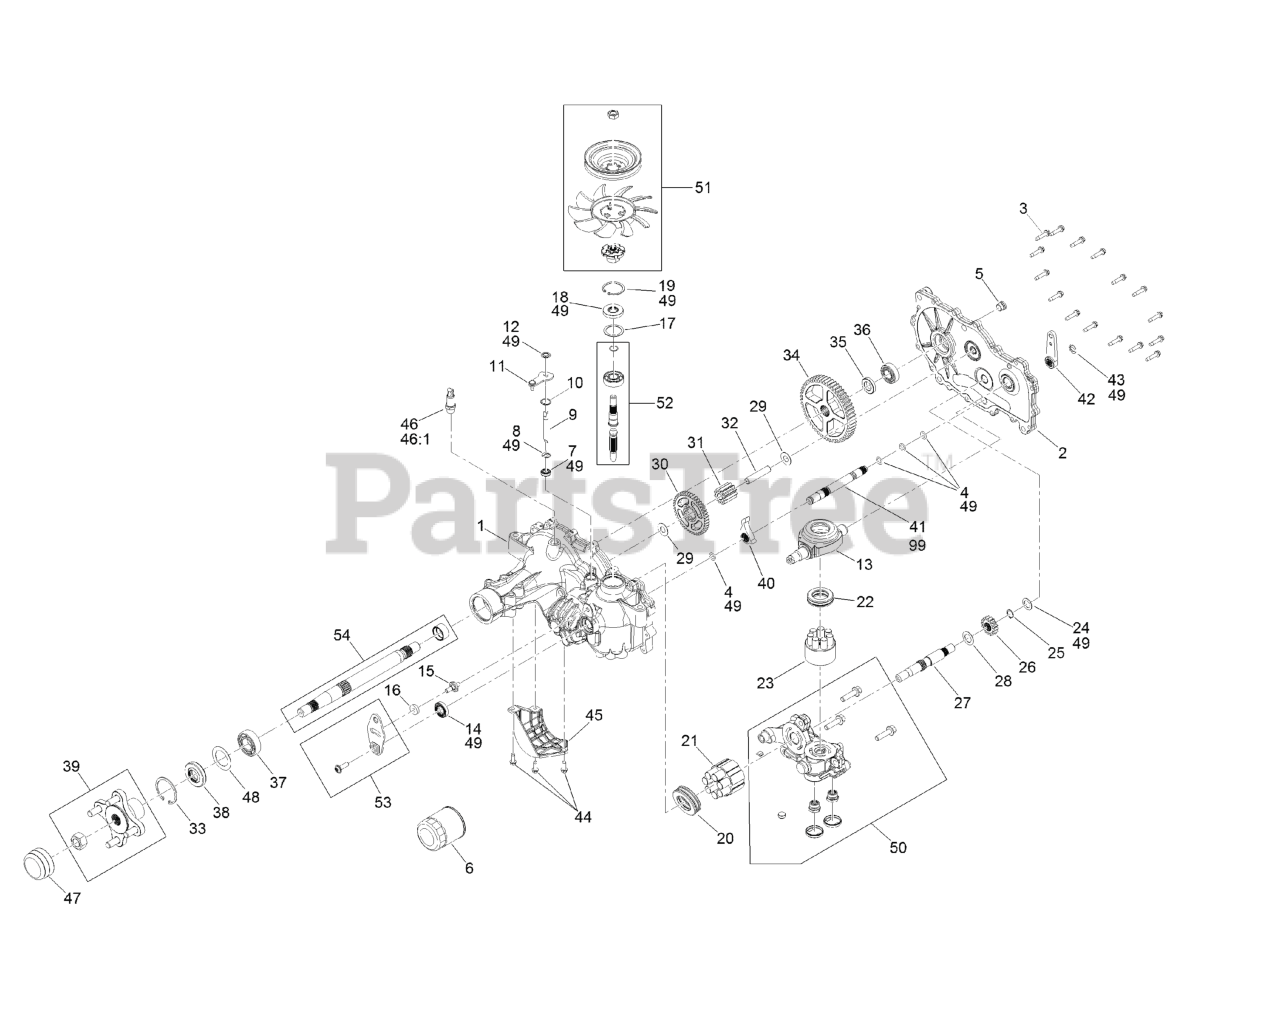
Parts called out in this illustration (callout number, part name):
1	MAIN HOUSING KIT
2	RH SIDE COVER KIT
3	SCREW-HHF
5	PLUG-THREAD, STRAIGHT
6	ELEMENT-OIL FILTER, HYD
7	SEAL-LIP
8	RING-RETAINING, EXTERNAL
9	ROD-BYPASS
10	RING-RETAINING, INTERNAL
12	RING-RETAINING, EXTERNAL
13	SWASHPLATE-TRUNNION
14	SEAL-LIP
16	PUCK-FRICTION
18	SEAL-LIP
19	RING-RETAINING
20	BEARING-THRUST
21	MOTOR CYLINDER BLOCK KIT
22	BEARING-THRUST
23	PUMP BLOCK ASM
24	WASHER-FLAT
25	RING-RETAINING
26	GEAR-16T
27	SHAFT-MOTOR
30	GEAR-43T
31	GEAR-11T
32	PIN-JACKSHAFT
33	RING-RETAINING
34	GEAR-54T
36	BEARING-BALL
37	BEARING-BALL
39	HUB KIT
40	PAWL-BRAKE
41	SHAFT-BRAKE, INBOARD
42	HANDLE-BRAKE
43	RING-RETAINING, EXT
45	GUARD-FILTER, RH
46	ADAPTER-STRAIGHT
46:1	O-RING
47	COVER-NUT, AXLE
49	SEAL KIT
50	RH CENTER SECTION KIT
51	FAN PULLEY KIT
52	INPUT SHAFT KIT
53	CONTROL ARM KIT
54	AXLE SHAFT KIT
99	BRAKE SHAFT SEAL KIT
